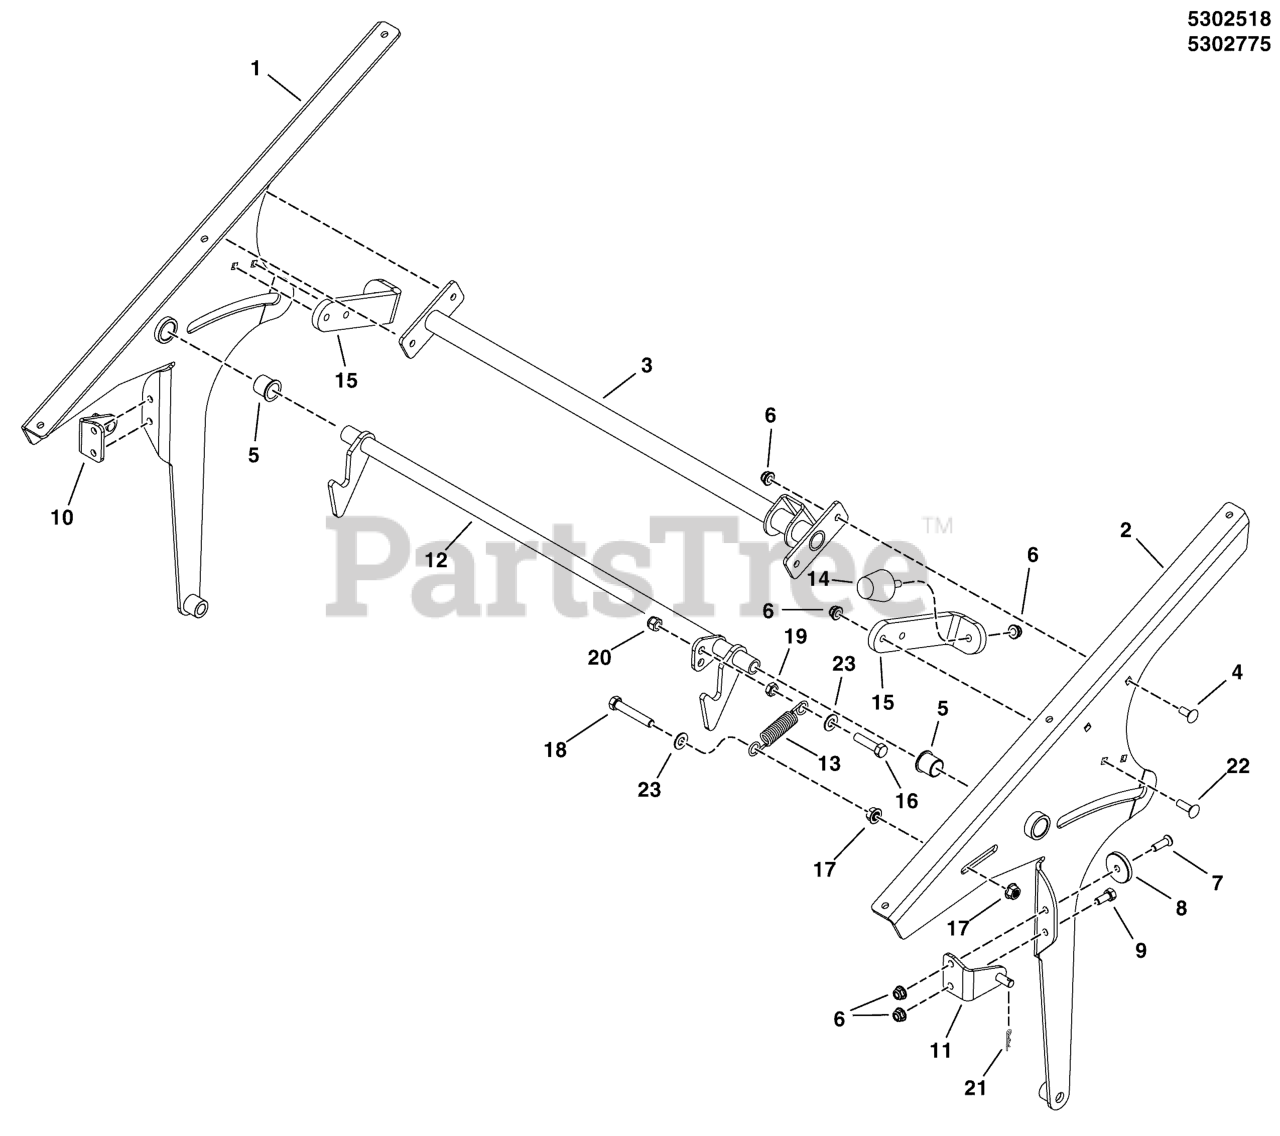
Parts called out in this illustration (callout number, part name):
3	WELD, TORSION BAR - BLK
4	BOLT, 5/16-18 X 3/4, CARRIAGE
5	BUSHING-0.765ID 0.885OD 0.877LG NYLON
6	NUT, 5/16-18 HEX NYLOCK FLANGE
7	SCREW, 5/16-18 X 1 PHILLIPS HD, BZ
8	SPACER, .34 X 1.54 X .25 UHMW
9	BOLT, 5/16-18 X 3/4 GD5
12	WELD, LATCH ASSY, CENTER - BLK
13	SPRING, EXTENSION
14	BUMPER, RUBBER 5/16-18
15	BAR, STOP, HOPPER - BLK
16	BOLT, 3/8-16 X 1-1/2" GD5 CZ
17	NUT, 3/8-16 HEX SERRATED FLANGE
18	BOLT, 3/8-16 X 2-1/4" GD5 CZ
19	NUT, 3/8-16 HEX JAM
20	NUT, 3/8-16 HEX NYLON LOCK
21	PIN, HAIR, .0585 X 1-1/8, 1/4 EYE, YZ
22	BOLT, 5/16-18 X 1, CARRIAGE
23	WASHER, 3/8 SAE
